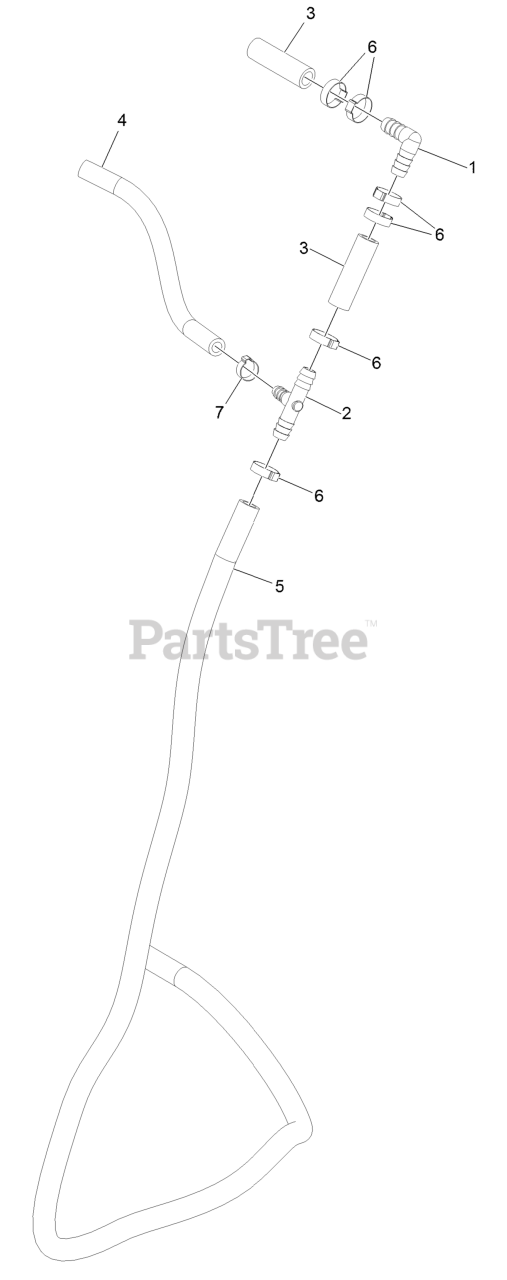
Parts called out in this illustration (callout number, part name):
1	FITTING-ELBOW-90
2	CONNECTOR-TEE
3	HOSE-WATER
4	HOSE-WATER
5	HOSE-WATER
